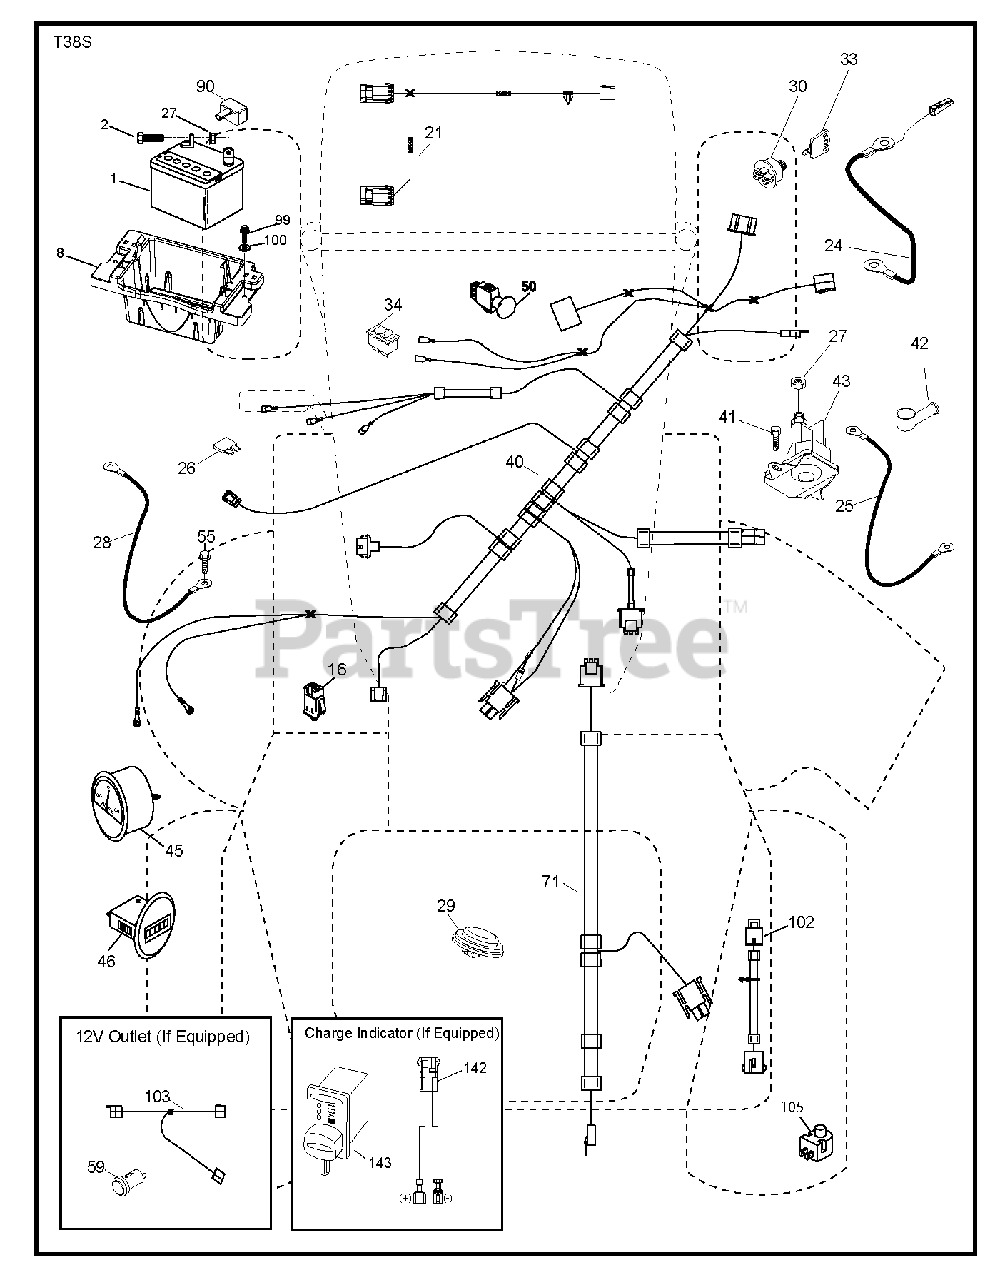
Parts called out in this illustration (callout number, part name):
1	Battery, Dry 30 Amp
2	BOLT.HEX.1/4.X.3/4.DICHROMATE
8	TRAY.BATTERY BOX.FRONT
16	SWITCH INTERLOOK PUSH-IN
21	HARNESS LIGHT ASSY TRACTOR,
24	CABLE.FRBATT.W/WIRE.8GA.8
25	CABLE.STARTER.8GA.17.5
26	FUSE 20AMP
27	NUT
28	CABLE.GROUND.21"BLK.8GA.90T
29	SWITCH.SEAT.DELTA.OPC.
30	SWITCH.IGN.DELTA.W.LGH.ROS
33	KEY.CHAIN.BLISTER.PACK.GEN.USA
40	HARNESS.IGN.DSH.W112V.WPORTWIR
41	SCREW
42	TERMINAL COVER
43	SOLENOID.STARTER.BRASS.PLUNGER
45	GAUGE.AMMETER.SILVER/WHITE
46	GAUGE.HOUR.METER.SILVER/WHITE
50	SWITCH.PTO.8TERMINAL.STD.BLK
55	SCREW 5/16"
71	HARNESS-CHASSIS SUB
90	COVER.TERMINAL.BATTERY
99	SCREW HEXWSHR 1/4-20X3/4
102	HARNESS PIGTAIL PCH TEX ROS
105	REVERSE SWITCH
